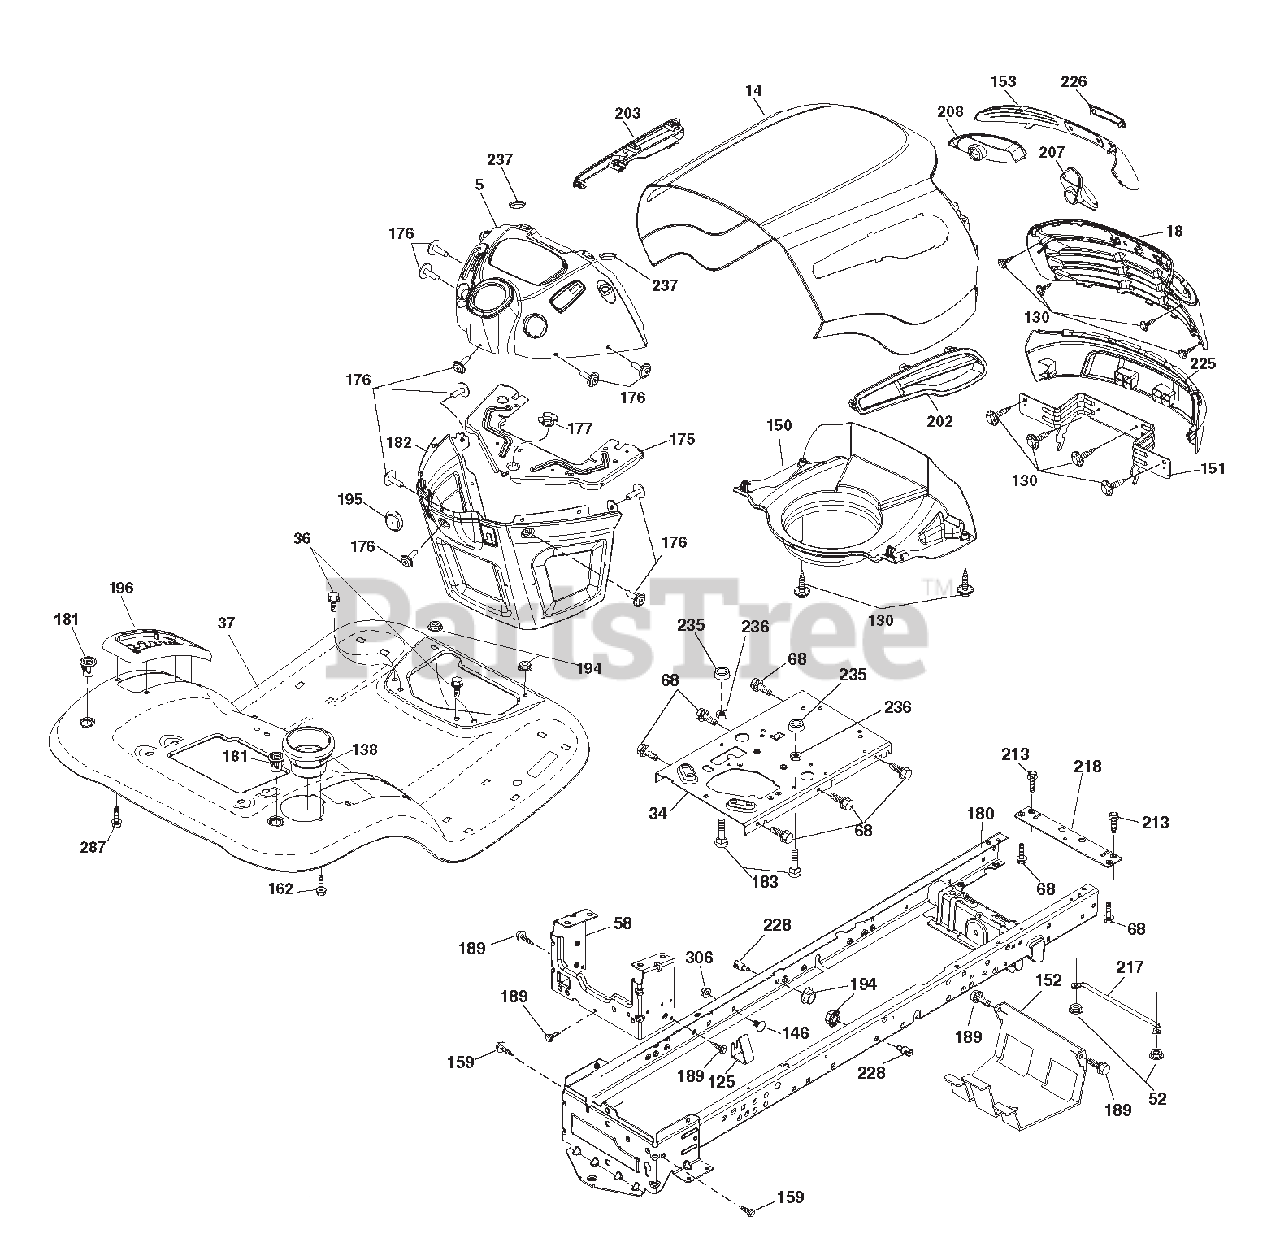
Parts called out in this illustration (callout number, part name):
5	DASH.P/L.TEX.CABLE
18	GRILLE.ELITE.ARIENS.BLACK
34	PLATE.ENGINE.WELDED.CHASSIS
36	SCREW.5/16-18X3/4.SMGML.TAP/R
37	FENDER.TLT W/CPH
52	Nut, Hex, Crownlock 5/16-18
58	DRAWBAR.UPPER.2PC.SML.FENDER
68	SCREW.THDROL.5/16-18 X 1/2TYTT
125	CLIP.FUEL.LINE
138	CUPHOLDER TL TEX 428
150	AIR DUCT
151	BRACKET.PIVOT
152	SHIELD.BROWNING.W/TEX
153	LENS.BAR
159	SCREW.HEXWSH THDR3/8-16X3/4.BL
162	SCREW.HEX.WSH.HI-LO.1/4X1/2UNC
175	CROSSMEMBER.LT
176	SCREW.#10-24X5/8.RND.QUDRX.GIM
177	BUSHING.STEERING.YT/GT
180	CHASS.WLDMT.TL.12GA/2PC.18/22"
181	BUSHING MNT FEND CRGO BLK TEX
182	DASH.LOWER.LT.CCS
183	BOLT.FIN.HEX.5/16-18 UNC X1-1/
189	SCREW.5/16-18X3/4.SMGML.TAP/BL
194	Nut, Lock Hex Flange 5/16-18 u
195	PLUG HOLE DASH TOWER
196	CONSLE.ASM.DECK.LFT.BL/RBT.TLT
202	VENT RH
203	VENT.SIDE.LH
207	BEZEL.LH
208	BEZEL.RH
213	BOLT.HEX.HD.1/4-20UNC X 3/4
217	ROD.PIVOT.HOOD
218	X-PIECE.HOOD.STOP.NON/STEALTH
226	ARIENS.LOGO.PLATE
228	STUD.FASTNER.W/'D'ANTI-ROTATIO
235	SPACER.FENDER
236	NUT.CENTER LOCK.5/16-18 UNC
237	PLUG.MOUNT.CARGO
287	SCREW.HEX.WASHEAD.1/4-20 X 3/8
306	Nut, Hex, Flangelock 3/8-16
